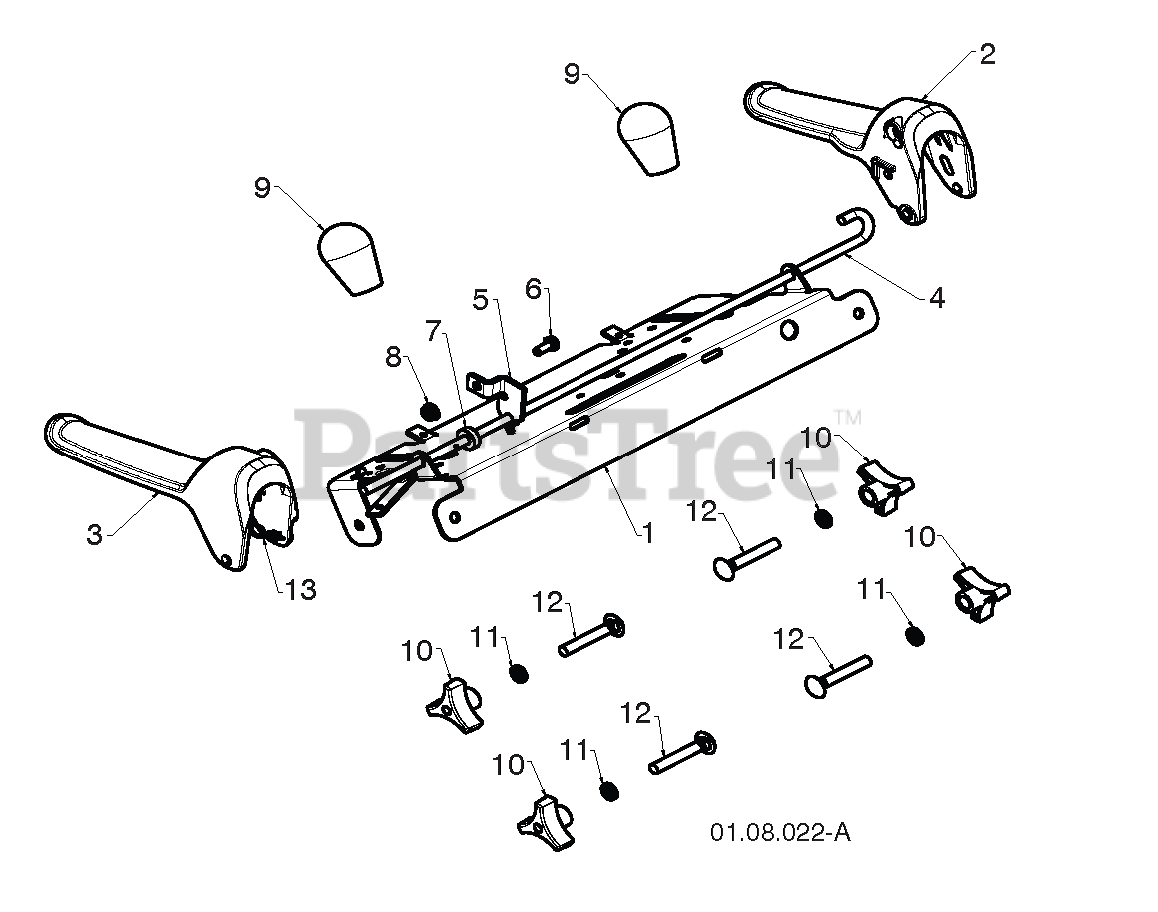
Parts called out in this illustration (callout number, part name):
1	PANEL.CONTROL.SNOW.BLACK
2	LEVER.CONTROL.LH.PL.BLACK
3	LEVER.CONTROL.RH.PL.BLACK
4	BAIL.CONTROL.INTERLOCK.SNOW
5	BRACKET.ARM.IMPELLER.ROD.YZ
6	BOLT
7	SPACER.CONTROL.LEVER
9	KNOB.OVERMOLD.DS.HUSQVARNA/BLK
10	KNOB.HANDLE.3/8.TRI-POINT.BLAC
11	WASHER
12	BOLT 3/8-16 X 2-1/4
13	SPRING RETAINER
